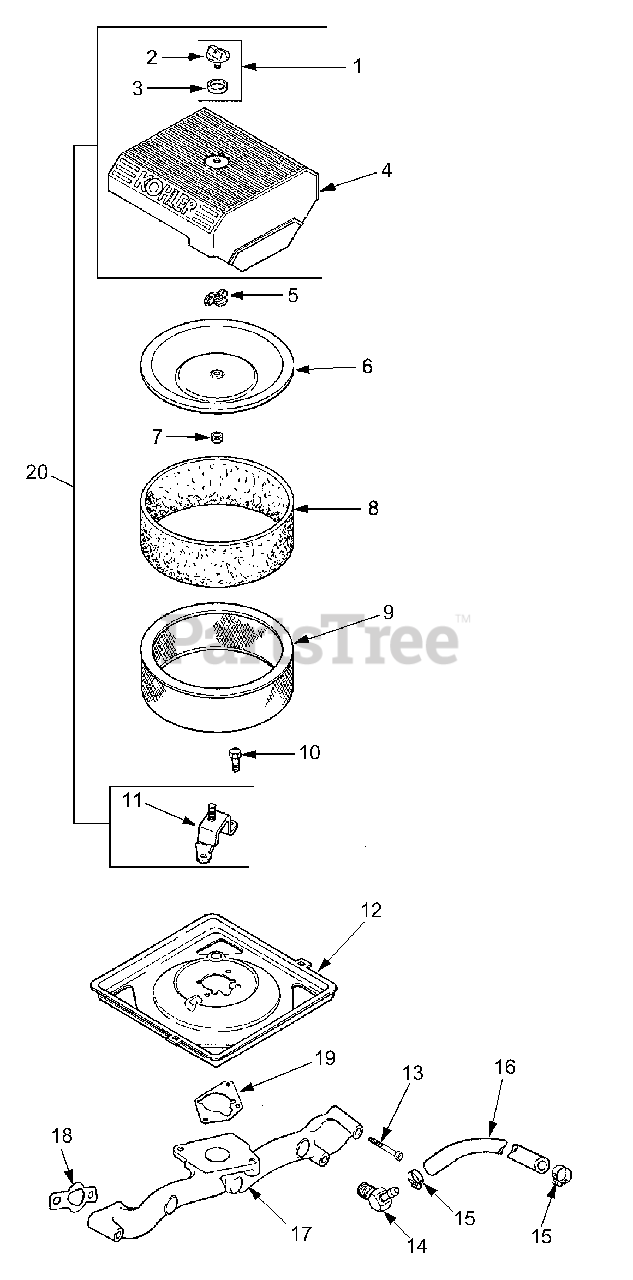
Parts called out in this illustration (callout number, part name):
1	Kit, Knob w/Seal
3	Seal, Air Cleaner Cover Knob
4	Cover, Air Cleaner
6	Cover, Inner Air Cleaner
7	Seal, Inner Air Cleaner
8	Precleaner, Element
9	Element, Air Cleaner
10	Screw, Hex Flange M6 x 1.0 x 16
11	Bracket, Air Cleaner Base
12	Base, Air Cleaner
13	Screw, Hex Flange M6 x 1.0 x 55
14	Connector, Hose 45°.
15	Clamp, Hose
16	Line, Fuel 17"
17	Manifold, Intake
18	Gasket, Intake Manifold
19	Gasket, Air Cleaner Base
20	Kit, Air Cleaner Cover
